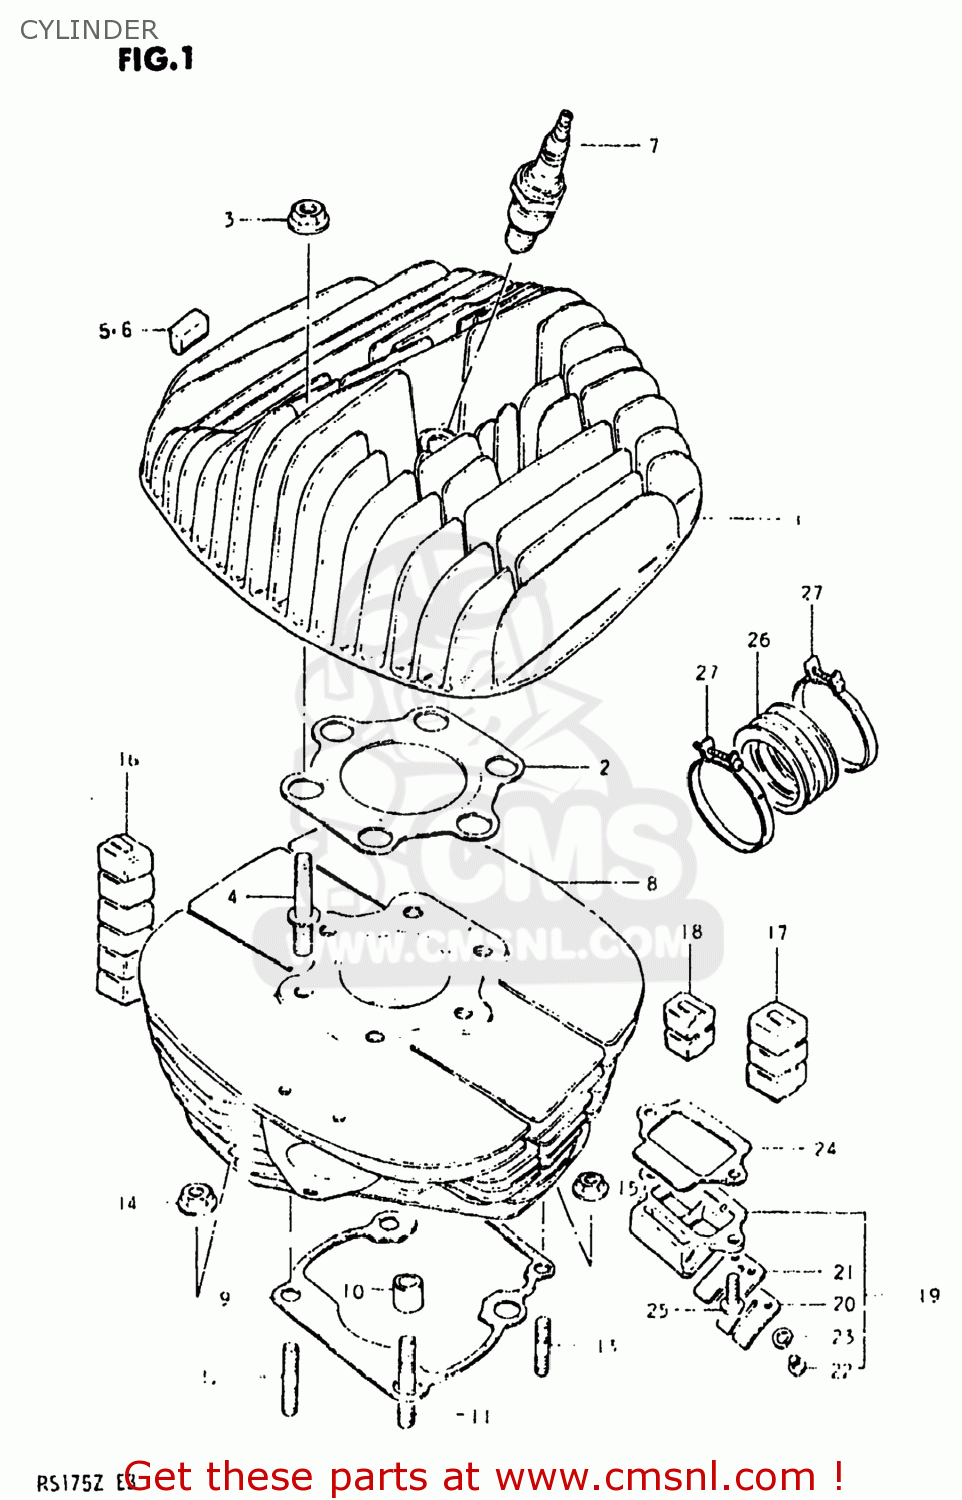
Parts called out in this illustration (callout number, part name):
1	HEAD,CYLINDER
2	GASKET,CYLINDER HEAD (NAS)
3	NUT
4	BOLT,STUD
5	PAD,CYLINDER
6	PAD,CYLINDER
7	PLUG,SPARK
8	CYLINDER
9	GASKET,CYLINDER (MCA)
10	PIN
11	STUD BOLT
12	STUD 8X25
13	STUD 6X25
14	NUT
15	NUT
16	PAD,CYLINDER
17	PAD,CYLINDER
18	PAD,CYLINDER
19	VALVE ASSY,REED
20	STOPPER,REED VALVE
21	VALVE,REED
22	SCREW
23	LOCK WASHER
24	GASKET,REED VALVE (MCA)
25	SCREW
26	PIPE,INTAKE
27	CLAMP
